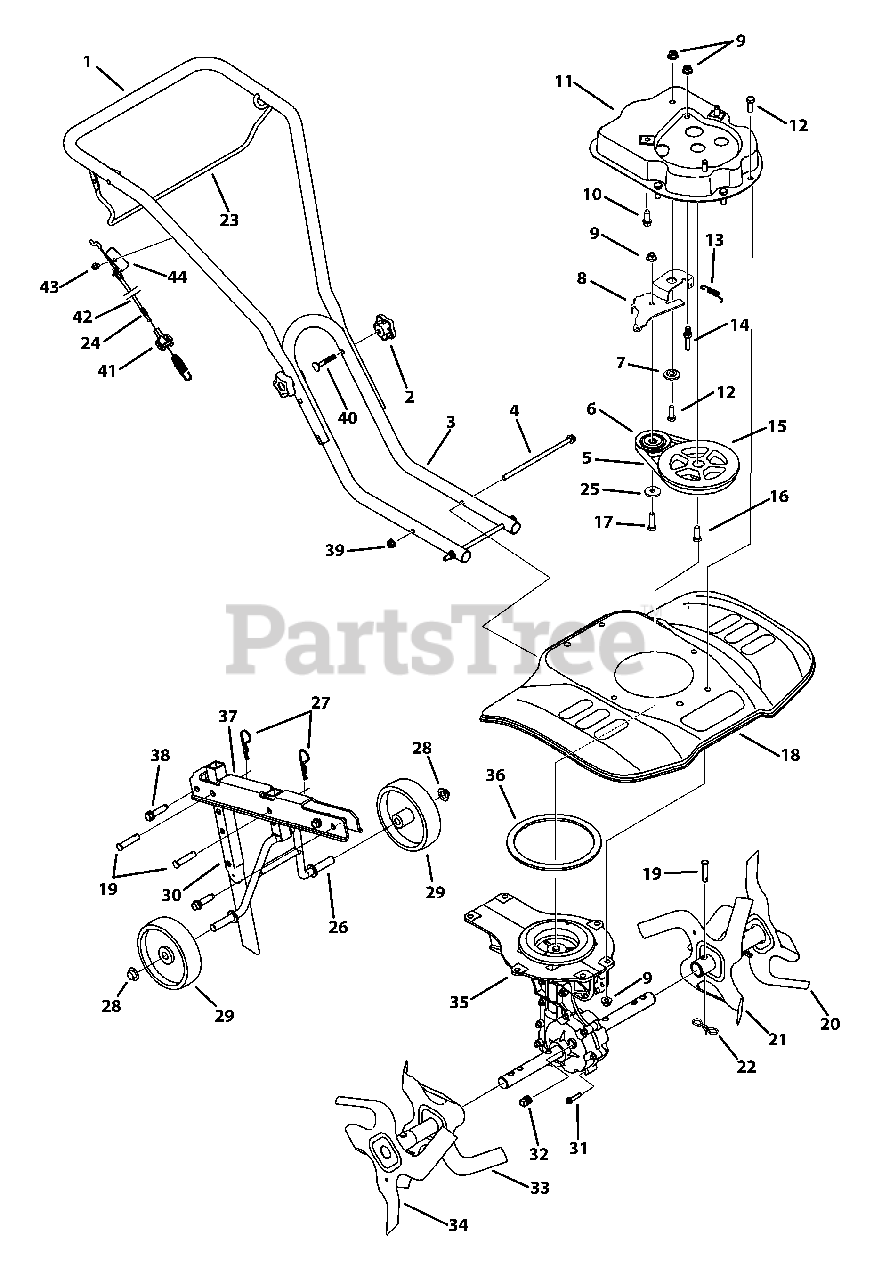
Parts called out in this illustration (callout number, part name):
1	Upper Handle
2	Star Handle Knob
3	Lower Handle
4	Flange Screw: 5/16-18:7.5:GR5
5	V-Belt
6	Idler Pulley
7	Shoulder Spacer
8	Idler Bracket
9	Flange Lock Nut: 3/8-16
10	TT Screw: 3/8-16:1.00
11	Belt Cover
12	Hex Cap Screw: 3/8-16:1.00
13	Extension Spring
14	Stud: 33 x 1.5: 3/8-16
15	Flywheel Pulley
16	Hex Cap Screw: 3/8-24:1.00
17	Hex Cap Screw: 3/8-16:1.55
18	Tine Shield 61 cm
19	Clevis Pin
20	Outer Tine Assembly LH
21	Inner Tine Assembly LH
22	Cotter Pin, Bow Tie
23	Clutch Bail
24	Retaining Ring
25	Flat Washer, .406 x .875 x .059
26	Rear Wheel Tube Assembly
27	Cotter Pin
28	Push Cap
29	Wheel 5 x 1.38
30	Depth Stake Tube
31	TT Screw: 1/4-20:1.25
32	Pipe Plug: 3/8 NPT
33	Inner Tine Assembly RH
34	Outer Tine Assembly RH
35	Case Assembly
36	Gasket
37	Wheel Bracket
38	TT Screw: 3/8-16:1.50
39	Flange Lock Nut: 5/16-18
40	Carriage Bolt
41	Clutch Cable Fitting
42	Clutch Cable
43	TT Screw: 1/4-20:.50
44	Cable Mount Bracket
